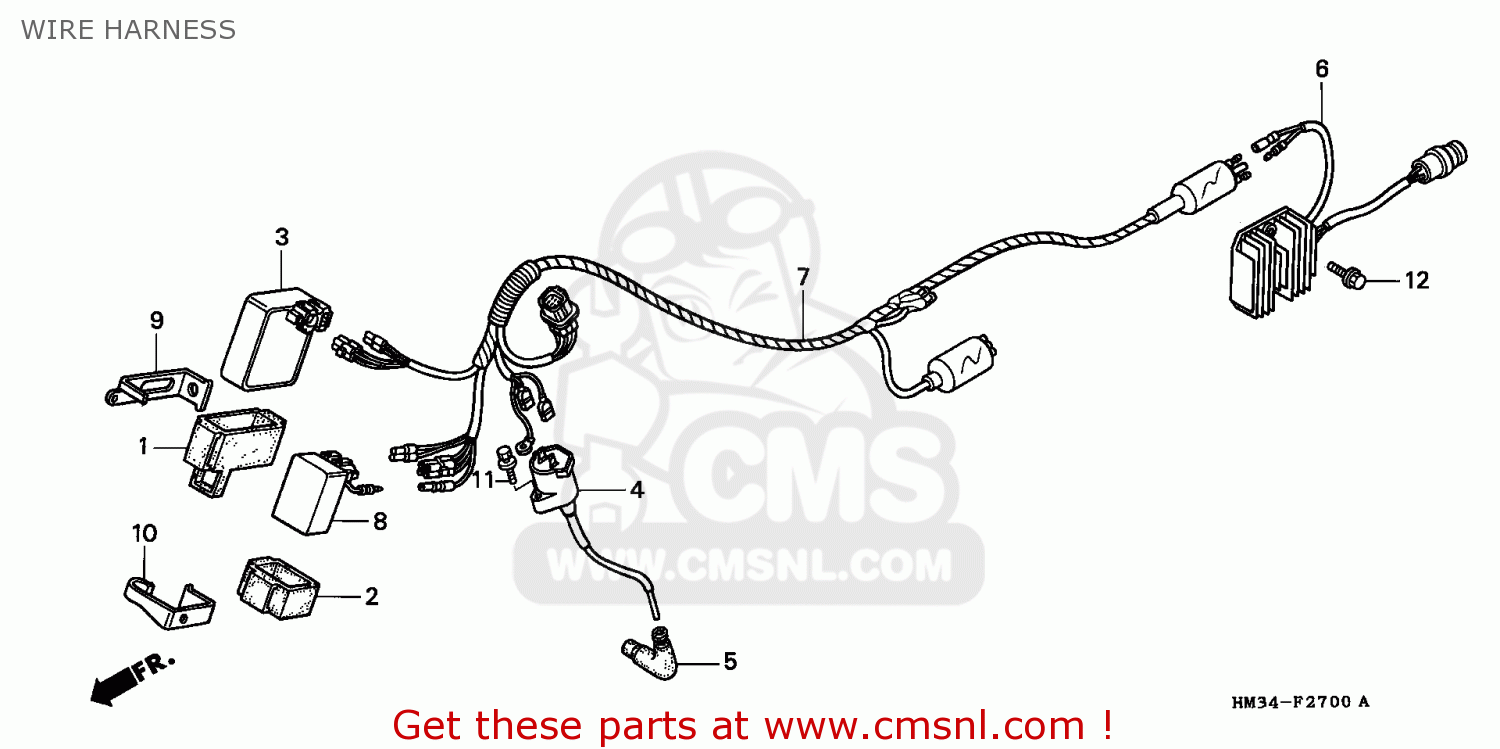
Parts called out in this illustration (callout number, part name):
1	CUSHION,C.D.I.UNI
2	CUSH,C.D.I UNIT
3	UNIT COMP,CDI(DC)
4	COIL COMP.,IGNITI
5	CAP ASSY NOISE (S
6	REG RECT ASSY
7	HARNESS,WIRE
8	UNIT COMP,RVS INH
9	BRACKET, C.D.I.
10	BRKT, INDICATOR UNIT
11	BOLT-WASH.,5X25
12	BOLT,FLANGE,6X14
